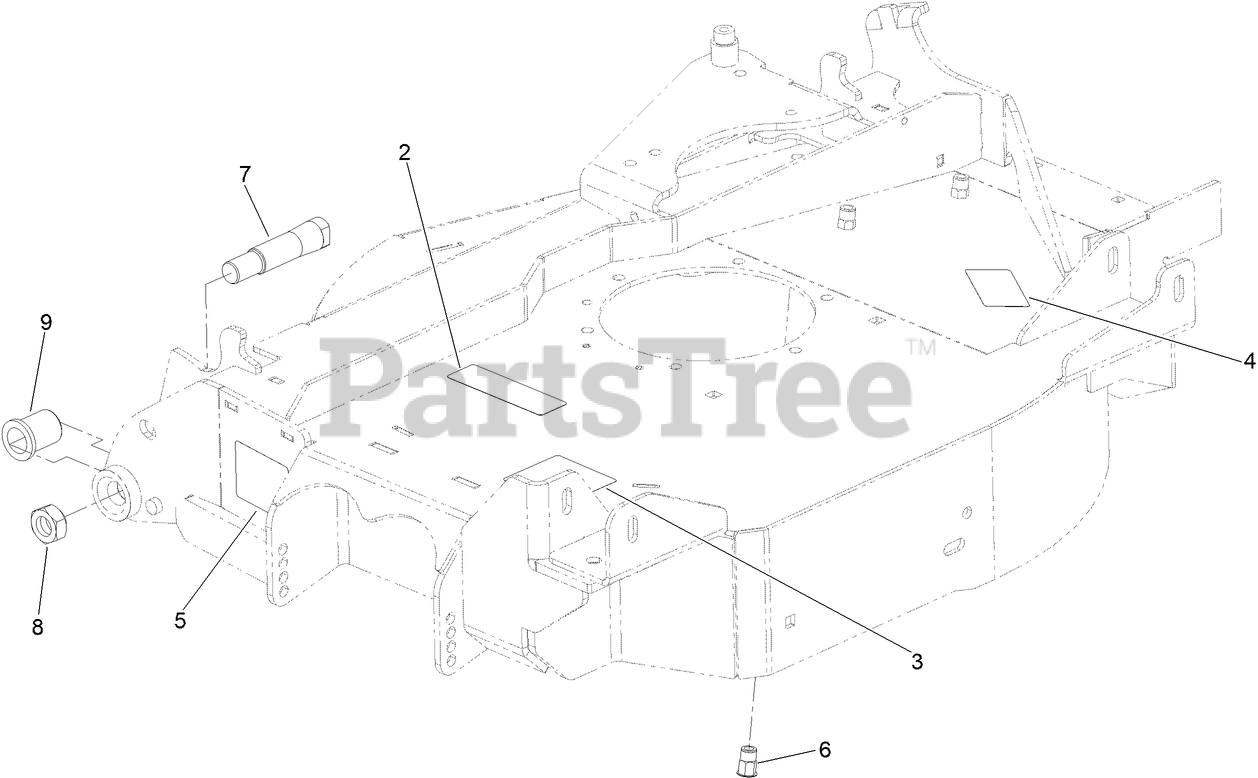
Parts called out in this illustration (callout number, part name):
2	DECAL-COVER, MISSING
3	DECAL-DANGER, THROWN OBJECT
4	DECAL-TORQUE, BOLT
5	DECAL-WARNING, PINCH POIN
6	NUT-CLINCH,HEX
7	BOLT-PIVOT PIN
8	NUT-LUG
9	BUSHING-FLANGED
